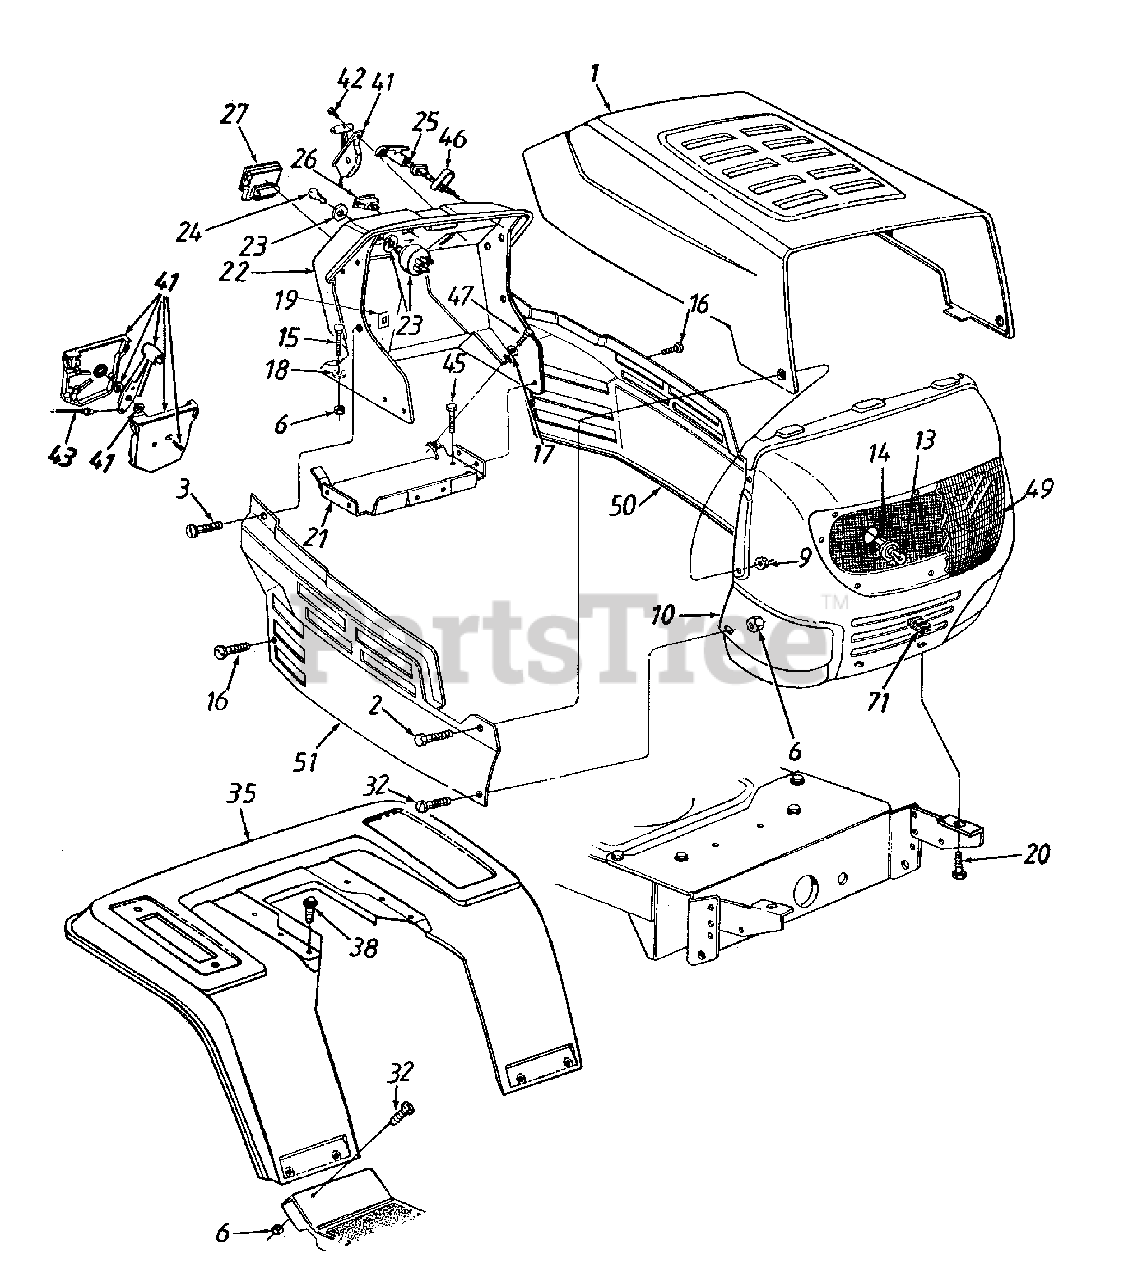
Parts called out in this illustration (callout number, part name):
6	Hex Sems Nut 1/4-20 Thd.
9	Flange Lock Nut 1/4-20 Thd.
13	Lamp
14	Socket
15	Carriage Bolt 1/4-20 x .75" Lg.
16	Hex Wash. Hd. TT-Tap Scr.1/4-20 x .5"
17	Flat Washer .281" I.D. x .73" O.D.
18	Bolt Retainer 1/4" I.D.
19	Speed Nut 1/4-20 Thd.
20	Hex Bolt 5/16-18 x .1" Lg.
23	Ignition Switch
24	Ignition Key
25	Choke Control 23" Lg.
26	Light Switch
27	Ammeter
32	Pan Hd. Scr. 1/4-20 x .75" Lg.
41	Throttle Box Assembly
42	Truss Mach. AB-Tap Scr. #10 x .5" Lg.
43	Throttle Control Wire 18.5" Lg.
45	Hex Wash. Hd. B-Tap Scr. 5/16-18 x .5"
46	Choke Retainer
47	Hex TT-Tap Scr. 1/4-20 x .75" Lg.
49	Lens
